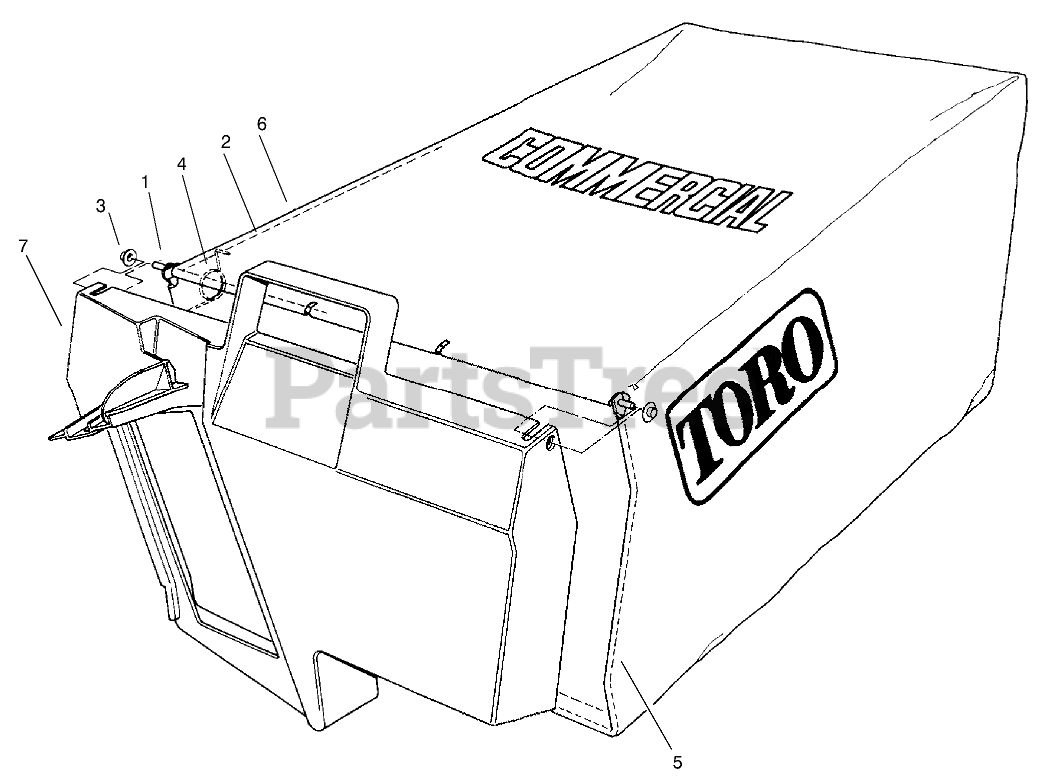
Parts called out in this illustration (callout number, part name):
1	Grass Bag ASM
1	HINGE-DOOR, BAG
2	FRAME-BAG, UPPER
3	NUT-PUSH
4	SPRING
5	FRAME-BAG
6	BAG-GRASS
7	DOOR-BAG, GRASS
